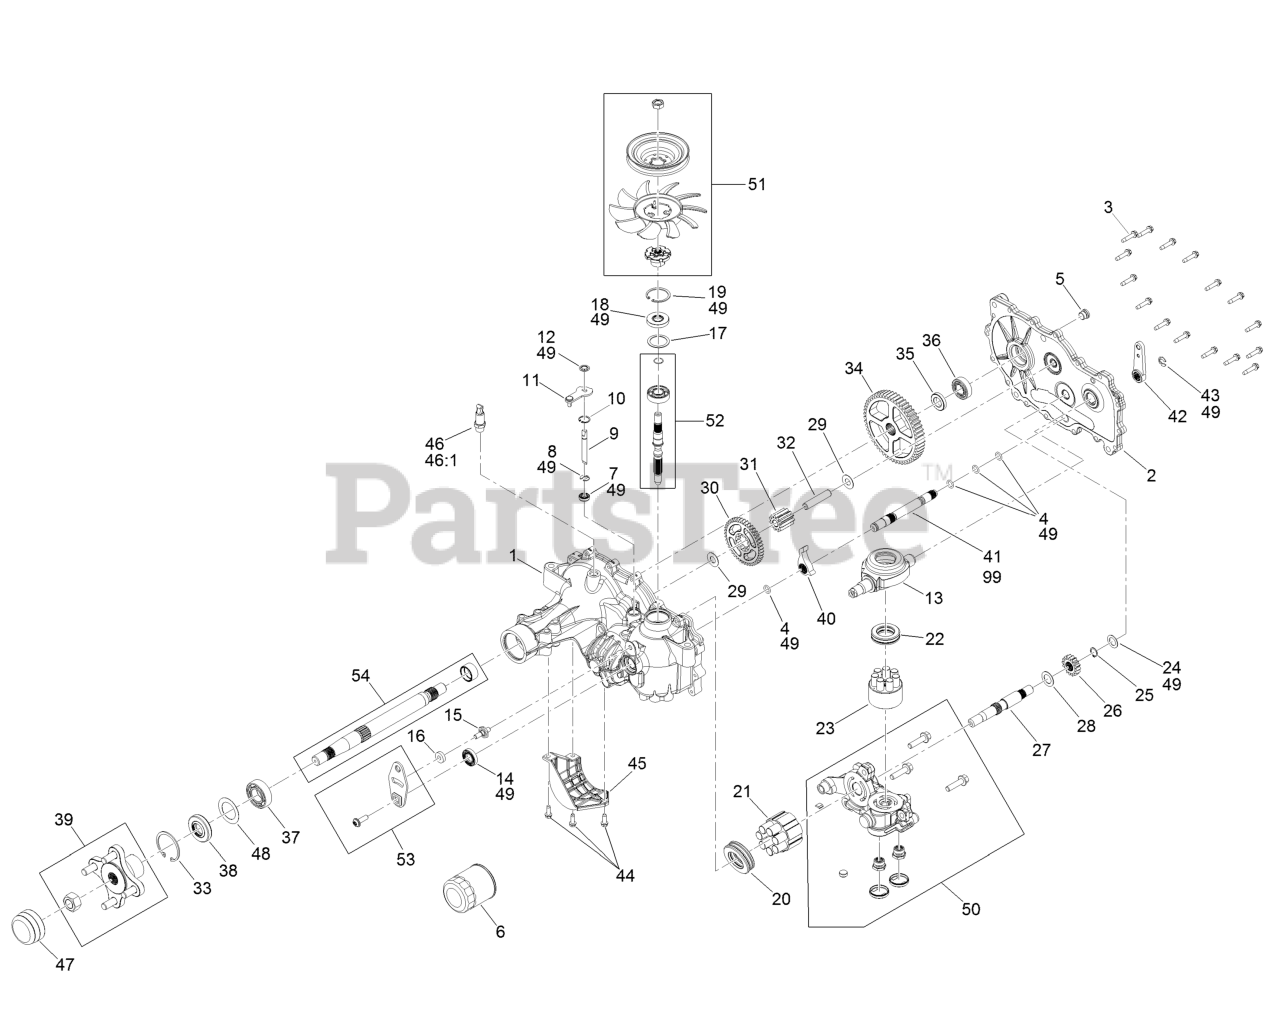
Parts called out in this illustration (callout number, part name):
1	Main Housing Kit
2	RH Side Cover Kit
3	Screw-HHF
5	Plug-Thread, Straight
6	Filter-Hydraulic
7	Seal-Lip
8	Ring-Retaining, External
9	Rod-Bypass
10	Ring-Retaining, Internal
11	Arm-Bypass
12	Ring-Retaining, External
13	Swashplate-Trunnion
14	Seal-Lip
16	Puck-Friction
18	Seal-Lip
19	Ring-Retaining
20	Bearing-Thrust
21	Motor Cylinder Block Kit
22	Bearing-Thrust
23	Pump Block ASM
24	Washer-Flat
25	Ring-Retaining
26	Gear-16T
27	Shaft-Motor
30	Gear-43T
31	Gear-11T
32	Pin-Jackshaft
33	Ring-Retaining
34	Gear-54T
36	Bearing-Ball
37	Bearing-Ball
39	Hub Kit
40	Pawl-Brake
41	Shaft-Brake, Inboard
42	Handle-Brake
43	Ring-Retaining, EXT
45	Guard-Filter, RH
46	Adapter-Straight
46:1	O-Ring
47	Cover-Nut, Axle
49	Seal Kit
50	RH Center Section Kit
51	Fan Pulley Kit
52	Input Shaft Kit
53	Control Arm Kit
54	Axle Shaft Kit
99	Brake Shaft Seal Kit
